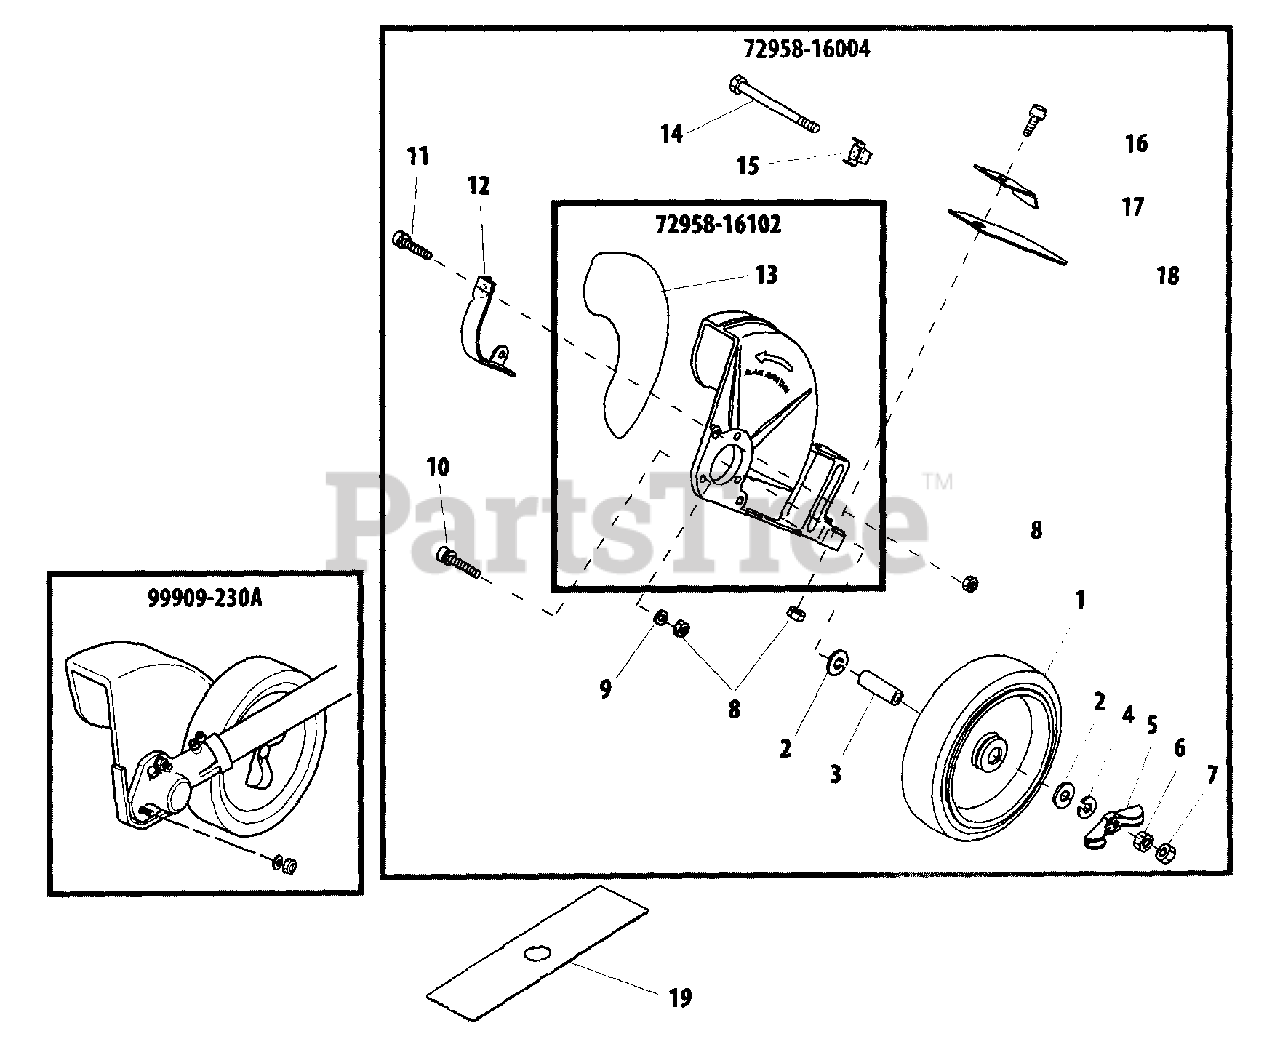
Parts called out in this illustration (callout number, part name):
1	WHEEL
2	WASHER
3	SLEEVE
4	WASHER, SPRING 8
5	KNOB, FASTENER
6	NUT M8
7	NUT, LOCK M8
8	NUT M5
9	WASHER, SPRING 5
10	BOLT M5×25
11	BOLT M5×12
12	PROTECTOR, GEAR CASE
13	LABEL
14	BOLT M8×90
15	PLATE, LOCK
16	BOLT M5×16
17	PLATE, FLAP
18	FLAP, DEBRIS
19	EDGER BLADE
72958-16004	GUARD ASSY
72958-16102	GUARD
99909-230A	GUARD/GEAR CASE KIT
